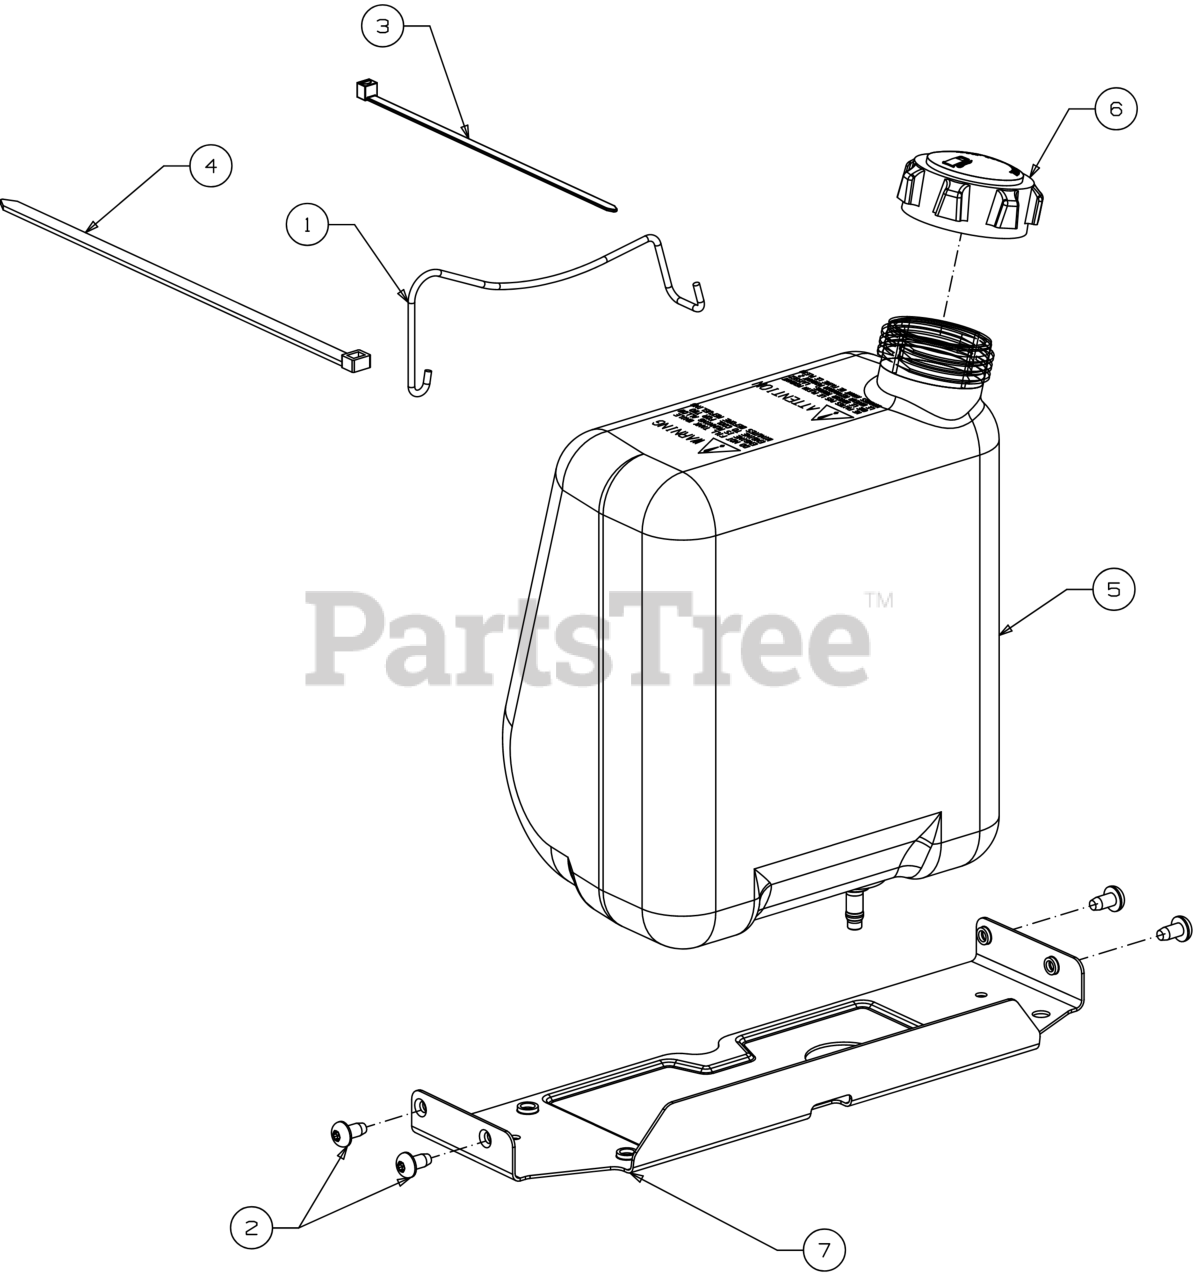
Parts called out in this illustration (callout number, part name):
1	BATTERY ROD ASSEMBLY (POWDER BLACK)
2	SCREW 1/4-20 x .5
3	7" CABLE TIE
4	CABLE TIE 36"
5	FUEL TANK 1.5 GAL
6	FUEL CAP (MAX 10% ETHANOL)
